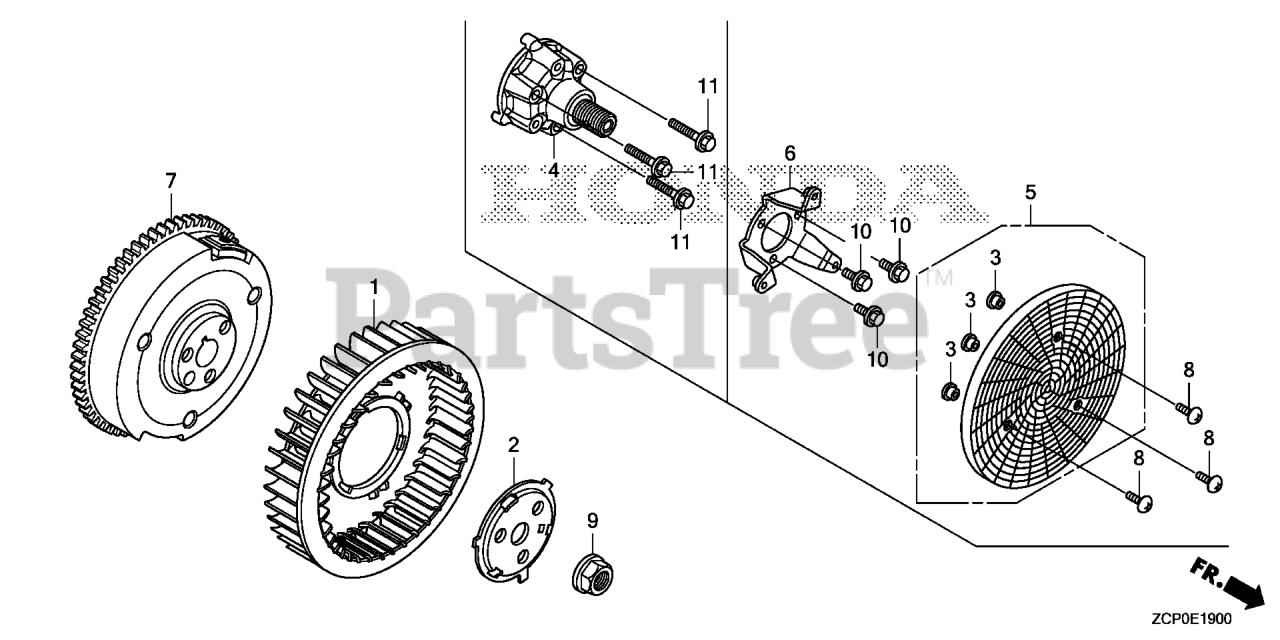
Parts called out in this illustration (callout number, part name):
1	FAN, COOLING
2	PLATE, COOLING FAN SETTING
9	NUT, SPECIAL (20MM)
